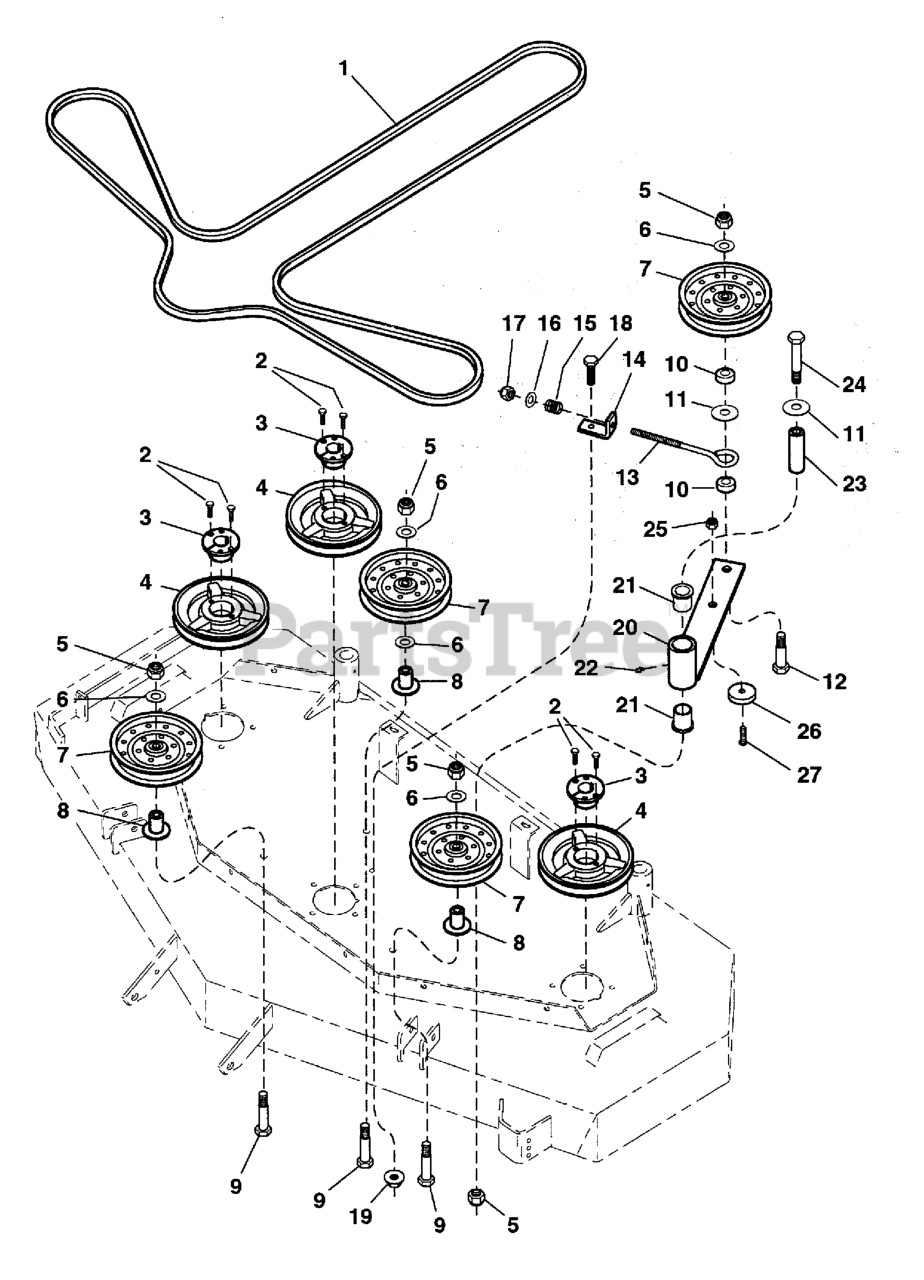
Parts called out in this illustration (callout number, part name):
1	BELT, 5V, 175.90EL, LG ARAMID, WRPD, RC
2	BOLT, 1/4-20 X 1" GD5 CZ
3	BUSHING, Tapered Hub
4	PULLEY, Spindle
5	NUT, 1/2-13 HEX NYLON LOCK
6	WASHER, 1/2 SAE
8	IDLER PULLEY MOUNT
9	BOLT, 1/2-13 X 3-1/2, HEX HD, GD5, CZ (SV)
10	SPACER, .52 x 1.00 x .44
11	WASHER, 1/2" USS
12	BOLT, 1/2-13 X 3" GD5 CZ
13	EYEBOLT, 3/8" x 8"
14	SPRING ANCHOR
15	SPRING, Compression
16	WASHER, 3/8 SAE
17	NUT, 3/8-16 HEX NYLON LOCK
18	BOLT, 3/8-16 X 1" GD5 CZ
19	NUT, 3/8-16 Hex Serrated Flange
20	IDLER ARM
21	BUSHING, FLANGE
22	GREASE FITTING
23	SPACER, .52 x 1.00 x 3.50
24	BOLT, 1/2-13 x 4-1/2
25	NUT, 5/16-18 Hex Nylon Lock
26	SUPPORT, Idler arm
27	SCREW, Flat Head, Socket, 5/16-18 x 1-1/4
